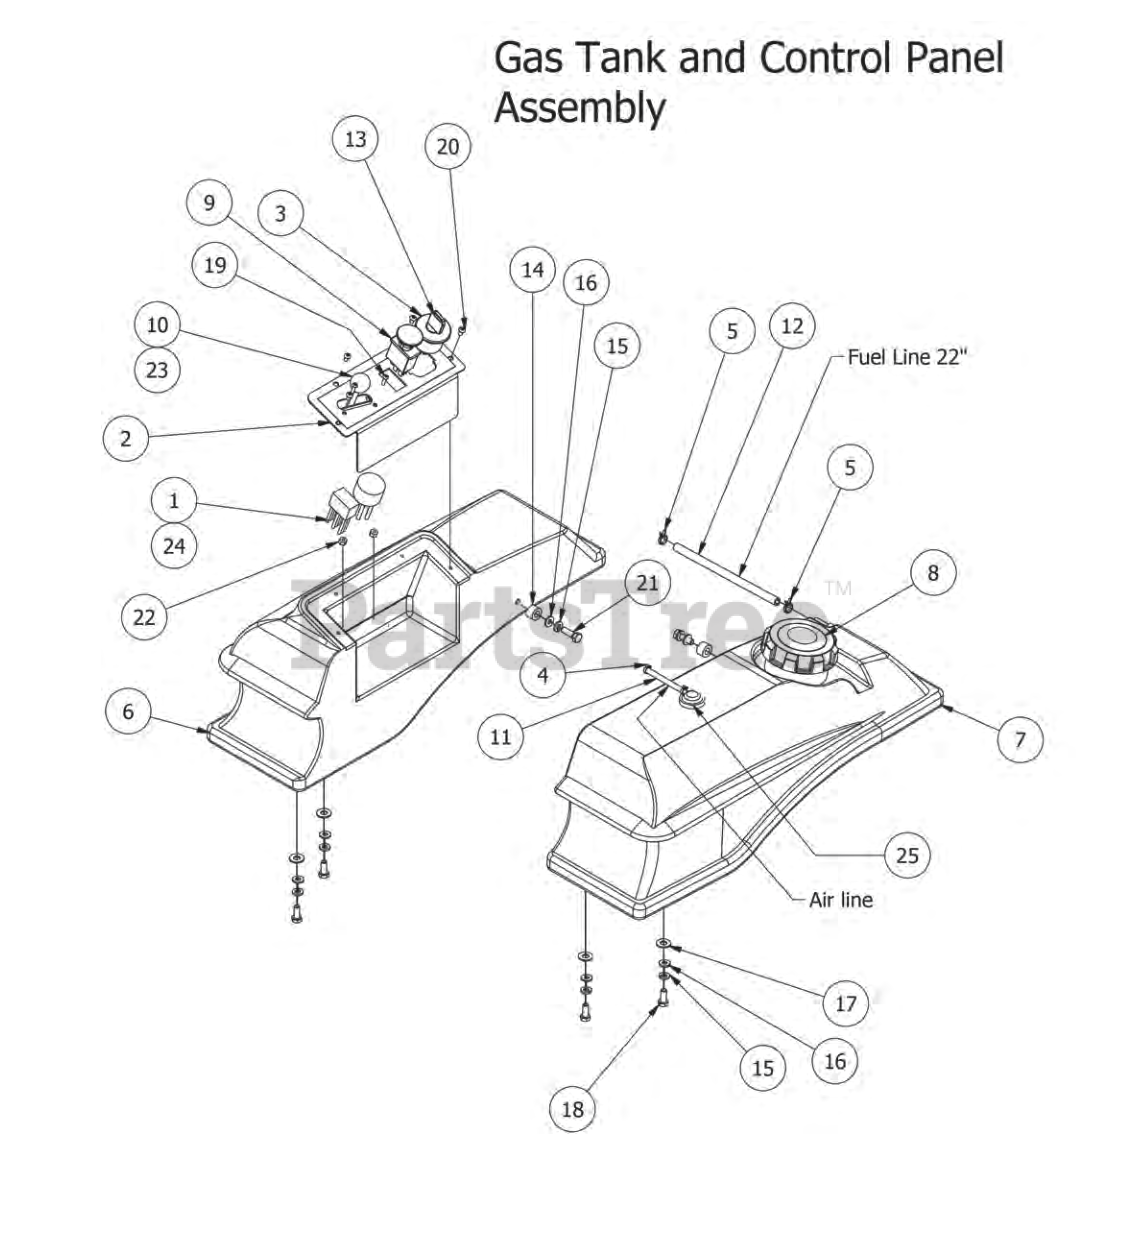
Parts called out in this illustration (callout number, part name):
1	Wiring harness
2	MZ Control Panel
3	Ignition Switch
4	1/4" vinyl clamp
5	1/4 fuel clamp
6	Fender Console
7	3 Gallon Fuel Tank/MZ/2012 EPA
9	PTO Engager
10	Throttle Lever W/Choke
11	1/4" vinyl tubing
12	1/4" fuel line hose sold by the Foot
13	Ignition Key
14	Tank spacer
15	5/16" Lock Washer
16	1/4" Flat Washer
17	.360 ID Plastic Washer
18	5/16" x 3/4" Hex Bolt
19	10-24 X 5/8 BS C/S 18-8 SS
20	10-32 x 3/8" Button Socket Head Bolt
21	5/16" x 1" Bolt
22	10-24 Nylon Insert Locknut
23	Throttle-21Hp MZ Only
24	Relay Terminal
25	Rollover Valve-White
